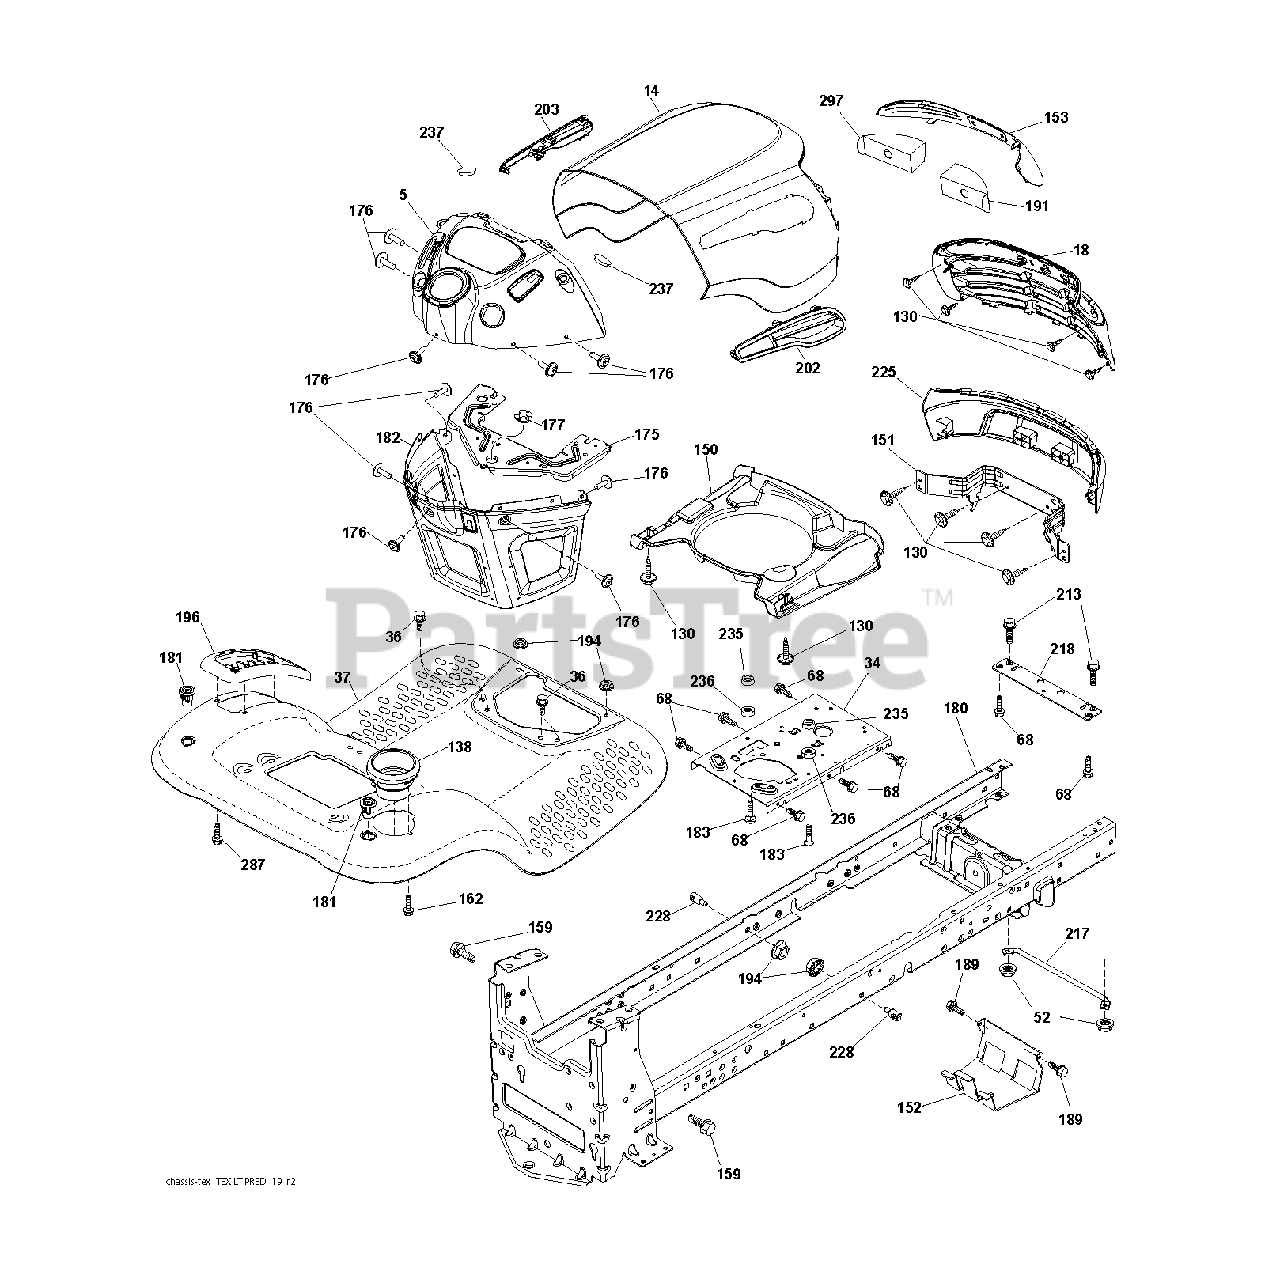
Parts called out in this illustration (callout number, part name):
34	PLATE.ENGINE.WELDED.CHASSIS
36	SCREW 5/16"
52	LOCKNUT
130	SCREW.#10 X 0.750.BOS THREAD
138	CUPHOLDER.TL.TEX.BLACK
151	BRACKET.PIVOT.ALPHA.LT
152	SHIELD BROWNING
159	SCREW, 3/8-16X3/4
162	SCREW.HI-LO.CONSOLE
175	CROSSMEMBER
176	SCREW.#10-24X5/8.RN.QU
177	BUSHING STEERING
180	CHASSIS
181	FEND/FTRST.PCH.CPH.NFW
182	DASH.LWER.PREDATOR/HUSQ.LT
183	BOLT.5/16-18X1-1/4 FULL.THREAD
189	SCREW
191	INSERT.REFLECT.PREDATOR.LT.RH
194	NUT LOCK HEX FLANGE 5/16-18
196	CONSOLE.ASM.DECKLFT.BL/RBT.TLT
213	BOLT
217	ROD.PIVOT.HOOD
218	X-PIECE.HOOD.STOP.NON/
228	STUD.FASTNER.W/ANTI-ROTATE
235	SPACER FENDER
236	NUT.CENTERLOCK.5/16-
237	PLUG.MOUNT.CARGO.BLK
297	REFLECTOR.INSERT.PRED.LH.LT
